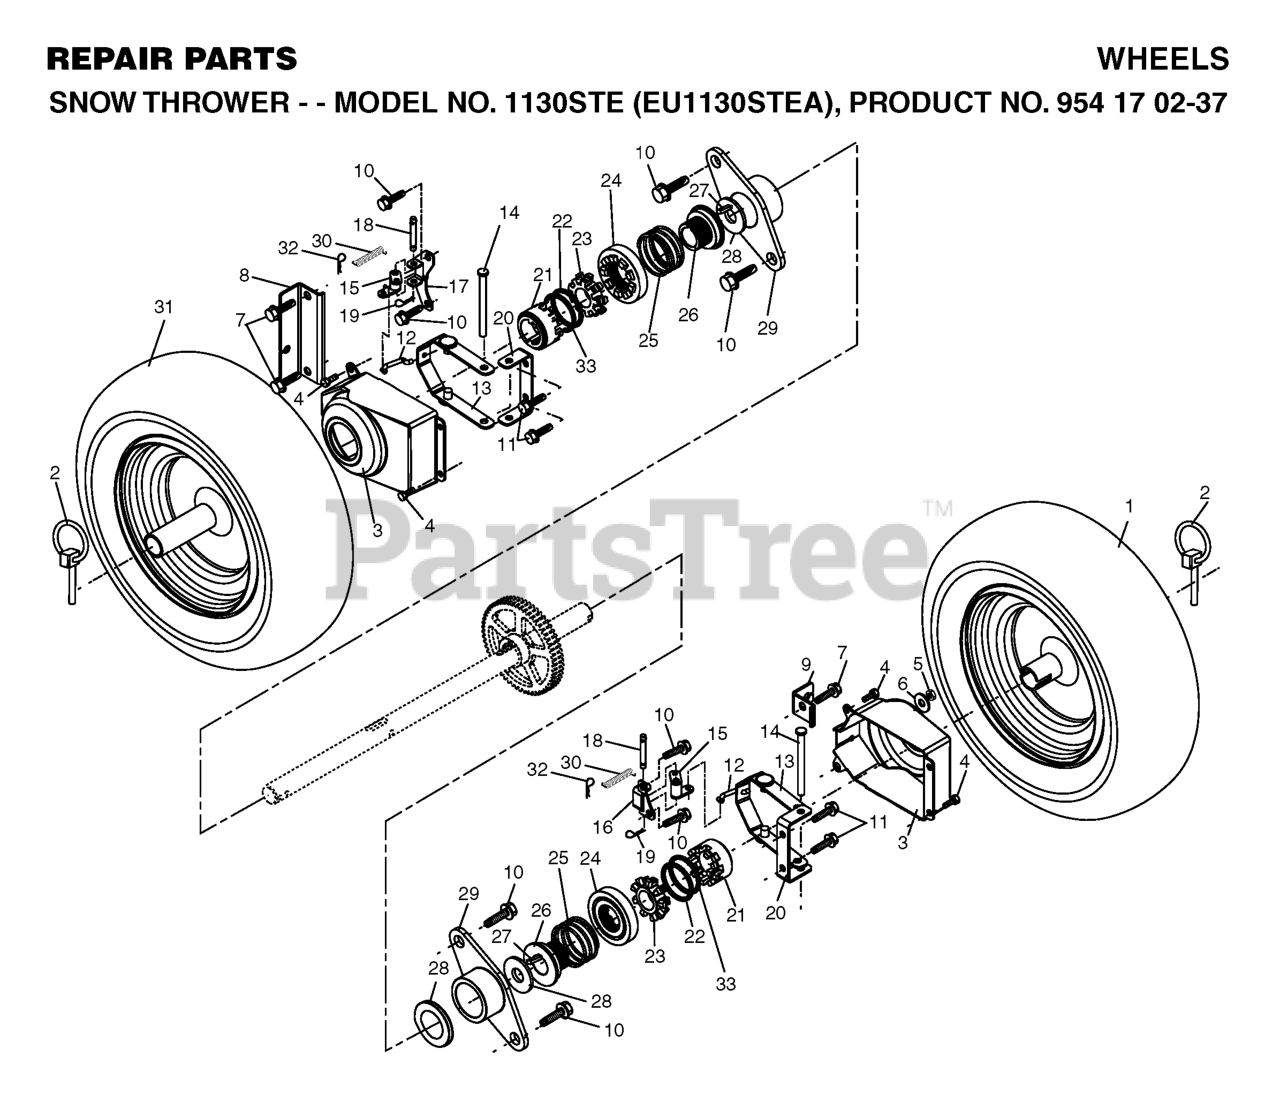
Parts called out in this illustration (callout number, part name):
1	WHEEL ASSY, 16" PWR STR LH
2	PIN KLIK, 1/4
3	COVER
4	SCREW, HEX HEAD, TAPPING
5	NUT.71038.31-18.HEX.NYLOCK
6	WASHER.20X8.5
7	Capscrew, Hex Head, Flanged 3/8-16 x 1
8	BRACKET, STEERING CABLE RH
9	BRACKET, STEERING CABLE LH
11	Screw 5/16-18 x 1/2 Hex, Self Tapping 5/16-18 x 1/2
12	LINK
13	YOKE, STEERING
14	PIN, STEERING LEVER
15	BELLCRANK WELDMENT
16	BRACKET ASS. LH STEERING
17	BRACKET ASSM RH STEERING
18	PIN, STEERING BELLCRANK
19	RETAINER CLIP PM
20	BRACKET.STEER.PNT.BLACK
21	DRIVER, WHEEL
22	RING, WIRE RETAINER
23	LOBE WHEEL
24	SLIDE CLUTCH
25	SPRING, CLUTCH SLIDE
26	LOBE.AXLE.SPLINED
27	KEY
28	WASHER TRUST 1"
29	BEARING, AXLE
30	SPRING
31	WHEEL ASSY, 16" PWR STRG RH
32	RETAINER CLIP
